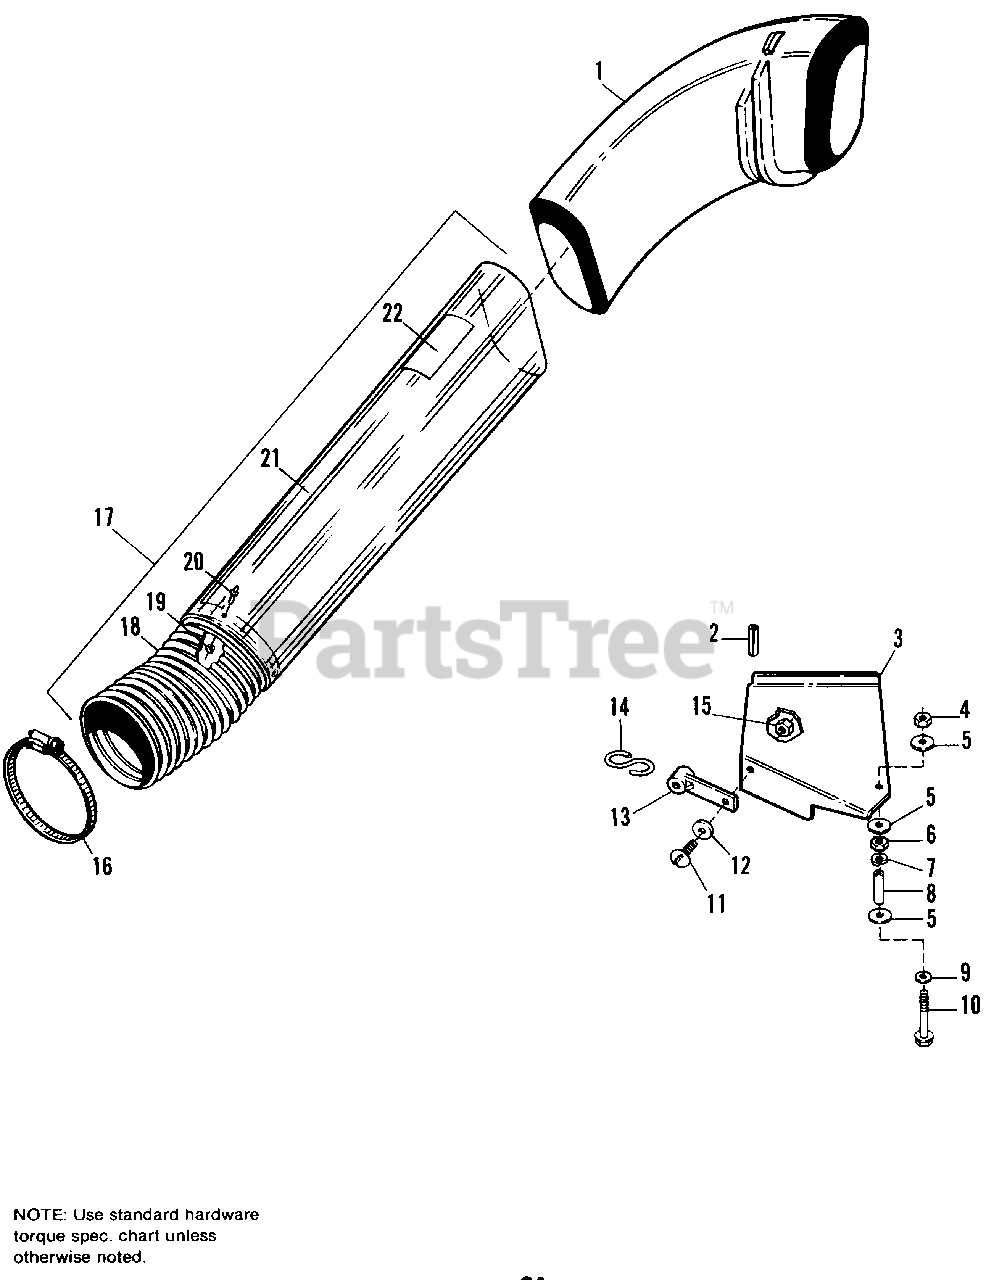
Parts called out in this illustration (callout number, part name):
3	COVER ASSY.
4	LOCKNUT, Hex, Full, 5/16-18
5	WASHER, Special
6	NUT, Hex, Full, 5/16-18
7	LOCKWASHER, 5/16
9	WASHER, Plain, 5/16
10	CAPSCREW, Hex, 5/16-18 x 5-1/2
11	SCREW, Truss Hd., #10-32 x 1/2
12	WASHER, Special
15	NUT, Hex, Full Lock, #10-32
16	CLAMP, "6" I.D.
17	TUBE ASSY., (Incl. Ref. Nos.18-22)
18	HOSE, "6" I.D.
19	WASHER, Rivet
22	DECAL, Cleaning Instructions
